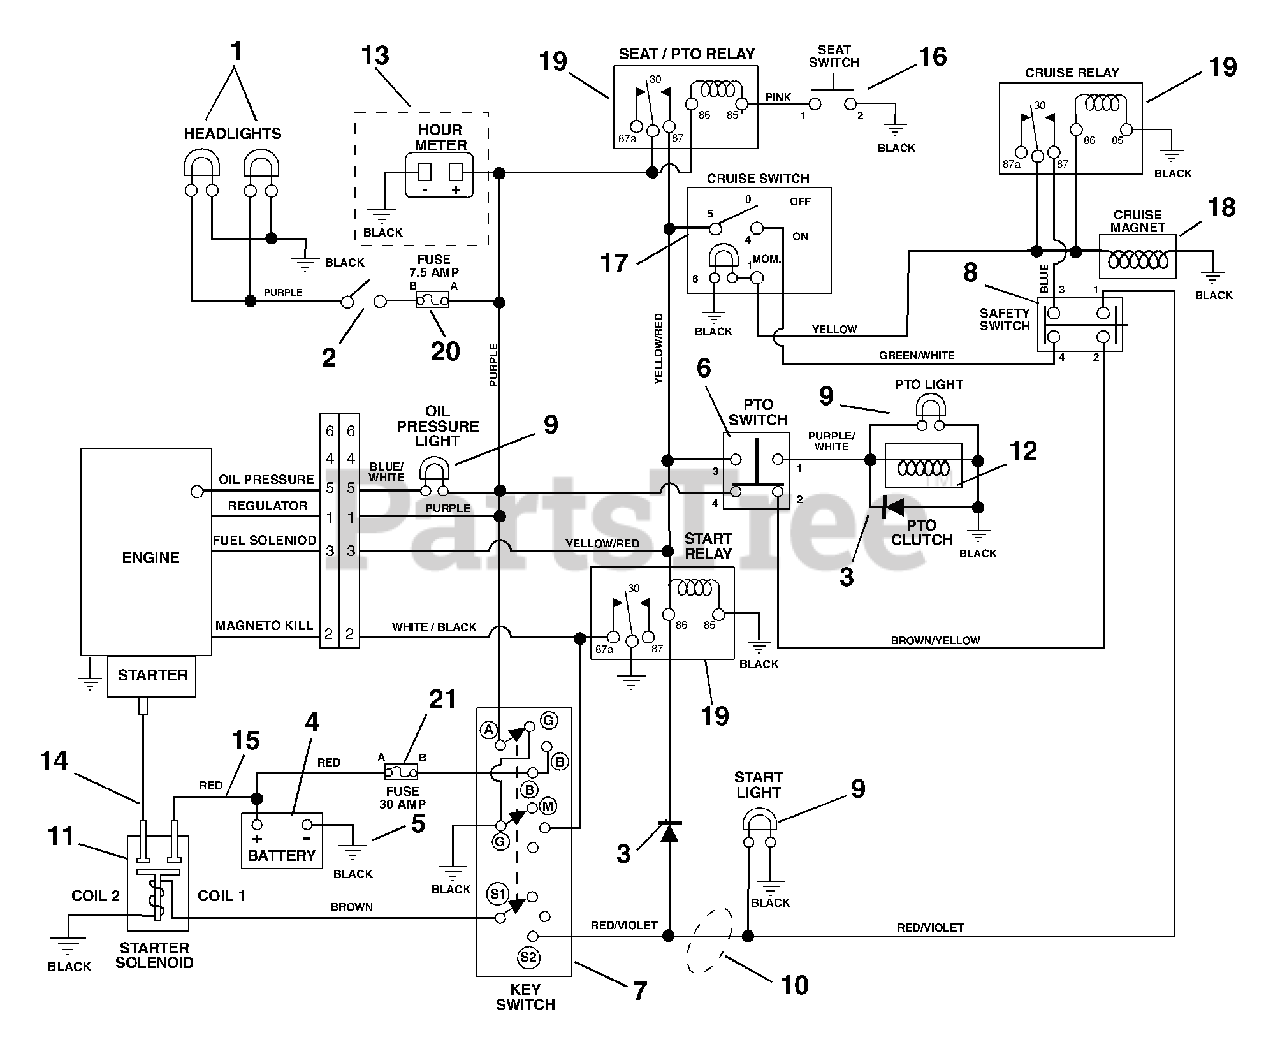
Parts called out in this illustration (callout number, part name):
1	HEADLIGHT BULB, 1156
2	SWITCH - LIGHT
3	MOLDED DIODE PLUG 1 AMP
4	BATTERY, 300 CCA 10U1L
5	GROUND CABLE .31X22.00X.31
6	PTO KNOB/ SWITCH ASSY
7	SWITCH KEY 5Y463A ALT GRDNG
8	SWITCH,INTERLOCK
9	BULB, #194
10	HARNESS, 6 PIN YT
11	SOLENOID
12	ELECTRIC CLUTCH/BRAKE (3.4AMP)
13	HOURMETER KIT- SIERRA
14	CABLE - START 22.00"
15	STARTER CABLE 6.75"
16	SWITCH- SEAT
17	SWITCH - CRUISE
19	RELAY
20	FUSE, 7.5 AMP
21	FUSE, 30 AMP.
